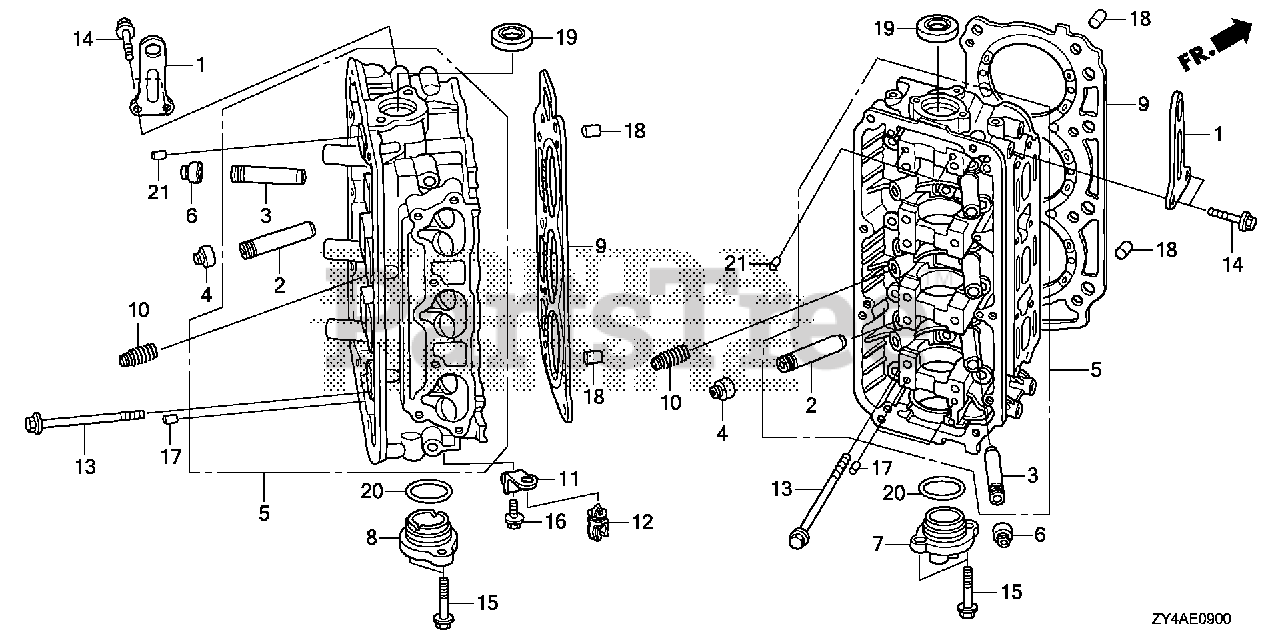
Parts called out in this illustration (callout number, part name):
1	HANGER, ENGINE
2	GUIDE, VALVE (OVER SIZE)
3	GUIDE, EX. VALVE (OVER SIZE)
4	SEAL A, VALVE STEM (NOK)
5	CYLINDER HEAD *NH8* (DARK GRAY)
6	SEAL B, VALVE STEM (NOK)
7	COVER, R. CAMSHAFT THRUST
8	COVER, L. CAMSHAFT THRUST
9	GASKET, CYLINDER HEAD (NIPPON LEAKLESS)
10	MOTION, LOST
13	BOLT-WASHER (12X163)
14	BOLT, FLANGE (8X20)
15	BOLT, FLANGE (8X28)
17	PIN, DOWEL (6X10)
18	PIN, DOWEL (16X22)
19	OIL SEAL (39X53X8) (NOK)
20	O-RING (48.5X2.4)
21	PIN B, DOWEL (6X10)
